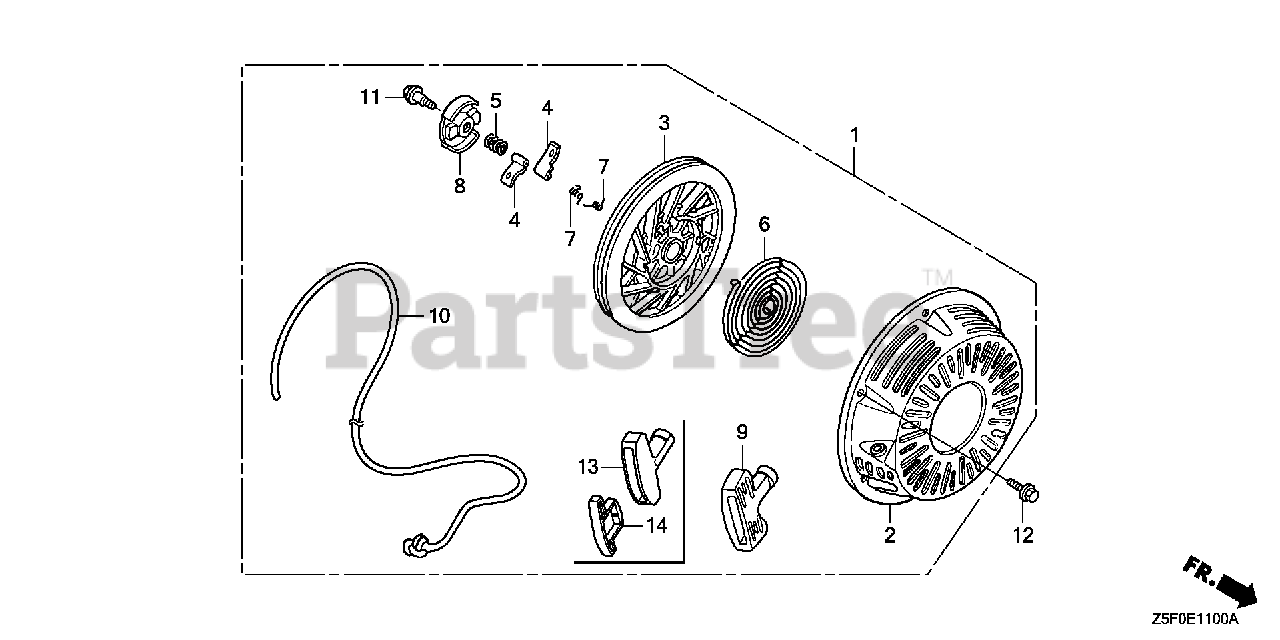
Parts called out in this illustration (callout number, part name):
1	STARTER ASSY., RECOIL *NH1* (BLACK)
1	STARTER ASSY., RECOIL *NH105* (MAT BLACK)
2	CASE, RECOIL STARTER *NH1* (BLACK)
2	CASE, RECOIL STARTER *NH105* (MAT BLACK)
3	PULLEY, RECOIL STARTER
4	RATCHET, STARTER
5	SPRING, FRICTION
6	SPRING, STARTER RETURN
7	SPRING, RATCHET
8	RETAINER, SPRING
9	GRIP, STARTER
10	ROPE, RECOIL STARTER (#5X55")
11	SCREW, CENTER
12	BOLT, FLANGE (6X10)
